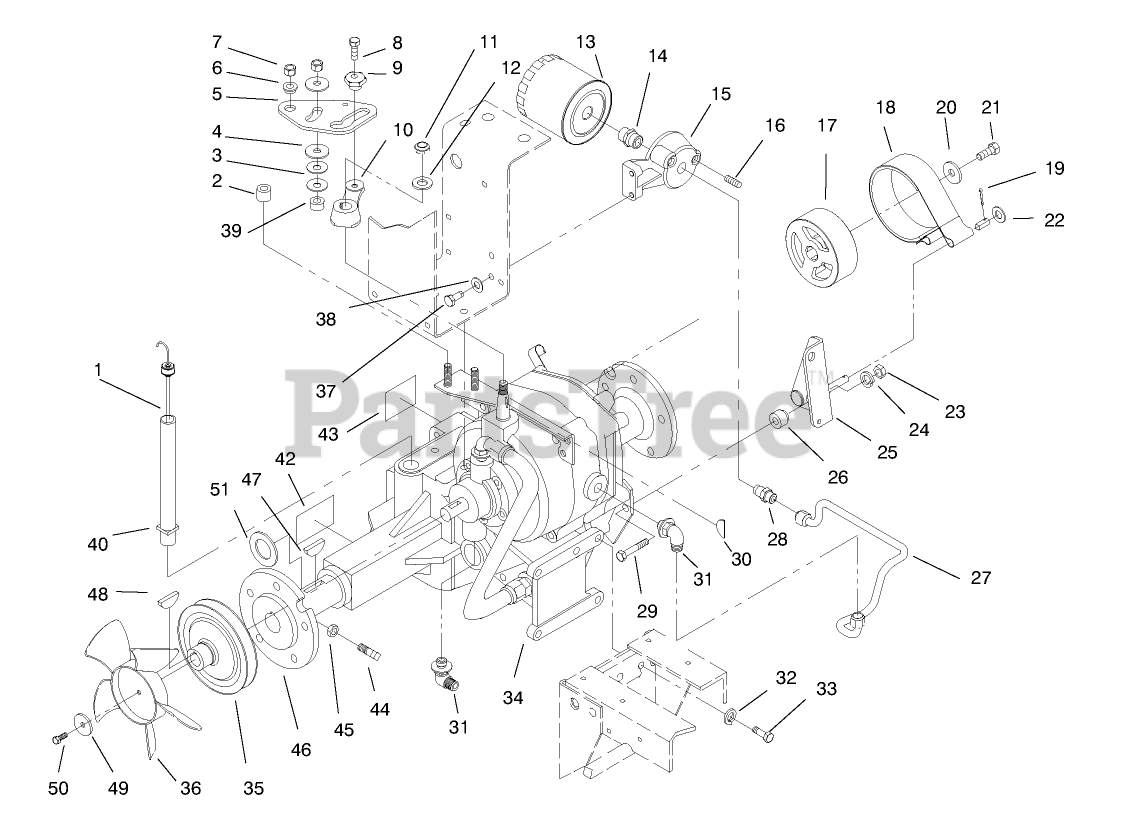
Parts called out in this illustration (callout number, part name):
2	Spacer-Pivot
3	WASHER-SPRING DISC
4	FRICTION WASHER
5	CAM-SPEED CONTROL (NS)
6	CAM-SPACER
7	NUT-HEX
8	Screw-HH
11	NUT-HEX
12	WASHER-FLAT
13	OIL FILTER ASM
14	FITTING
15	BASE-FILTER
17	DRUM-BRAKE
18	ASSY-BRAKE BAND
19	PIN-COTTER
20	WASHER
21	SCREW-HH, LOCK
22	WASHER-FLAT
23	NUT-LOCK, NI
24	WASHER-FLAT
25	Pivot Arm-Brake
28	FITTING
29	SCREW-HH
30	KEY-WOODRUFF
32	WASHER-LOCK
33	SCREW-HH
35	PULLEY
36	NYLON FAN-L-CW
37	SCREW-HH
38	WASHER-LOCK
39	SPACER-FRICTION
40	NIPPLE-TRANS FILL
42	DECAL - DANGER
43	DECAL-UNIDRIVE
44	SCREW-SET, SQH
45	NUT-JAM
46	HUB-WHEEL
47	KEY-WOODRUFF
48	KEY-WOODRUFF
49	WASHER
51	WASHER-THRUST
